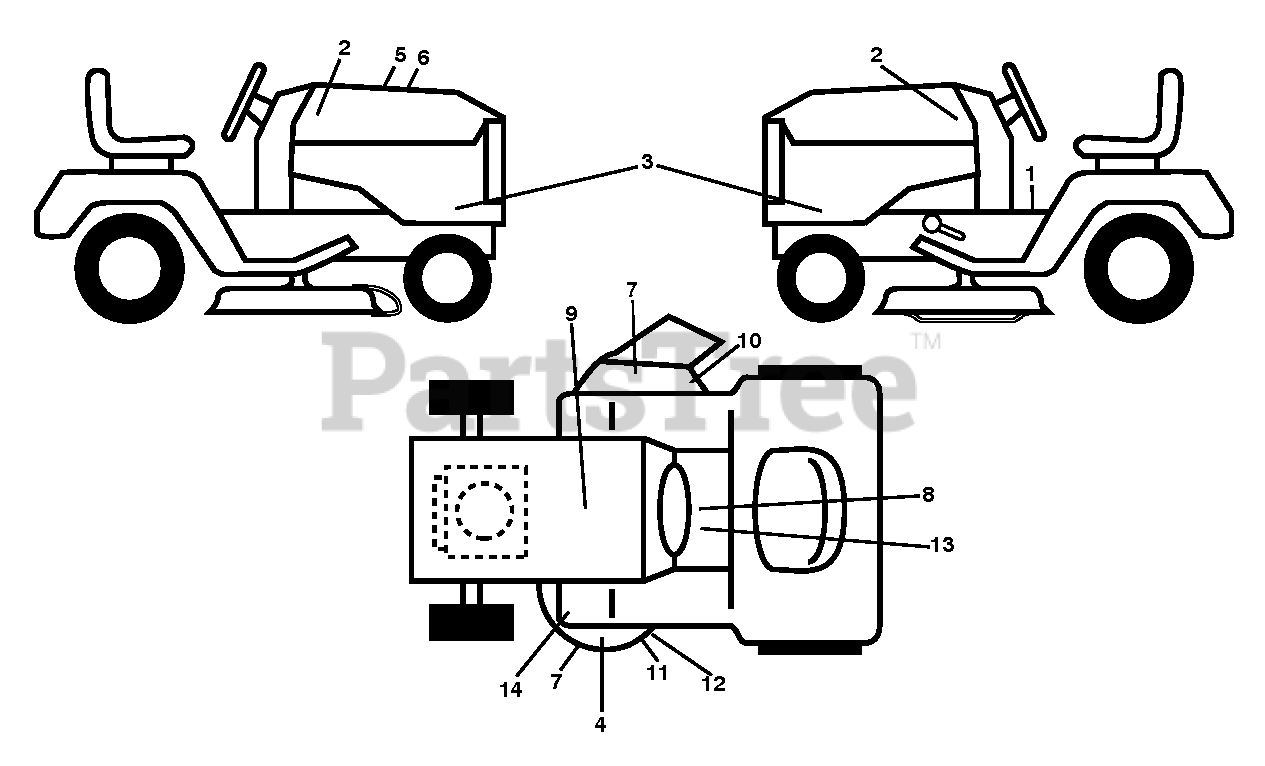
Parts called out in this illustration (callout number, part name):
1	DECAL.FENDER.WARNING
2	RP.DECAL.BADGE.170MM.TEXTLOGO
3	DECAL.SDPNL.GT2.YT42XLS.SET
4	DECAL.HV.REINFORCED.DECKS.2012
5	DECAL.WARNING.CUST.RESP.E85.
7	DECAL, NO STEP
8	DECAL, WARNING SPARK ARRESTOR
9	DECAL BTRY SYMBOLS
10	DECAL, CAUTION
11	DECAL.MOWER.SCH.48/54
12	DECAL.WARN.KEEP.HAND.AWAY
13	LABEL.EMISS.CALIF.HUSQVARNA
14	DECAL.PEDAL.HUSQ.CROWN
